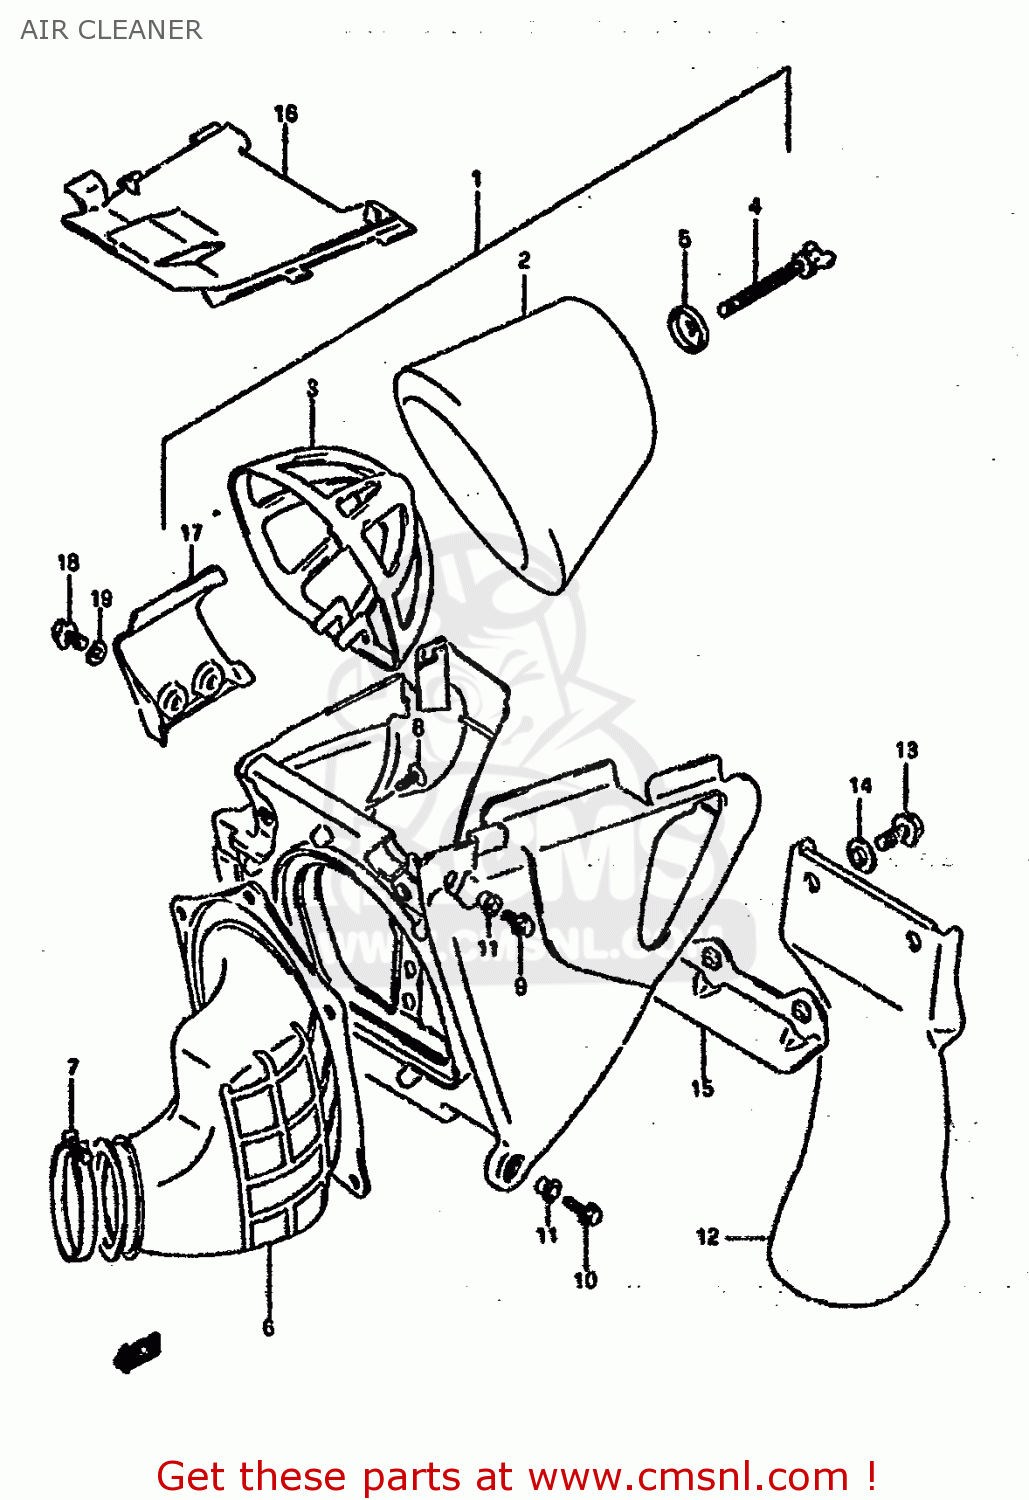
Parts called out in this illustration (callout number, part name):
1	CLEANER ASSEMBLY
2	FILTER ASSY
3	HOLDER,FILTER
4	BOLT,WING
5	WASHER,AIR CLEANER
6	TUBE,OUTLET
7	CLAMP
8	SCREW
9	BOLT
10	SCREW
11	WASHER
12	GUARD,MUD
13	BOLT
14	WASHER
15	PLATE,MUDGUARD
16	CAP,AIR CLEANER
17	COVER,AIR CLEANER,R NO.2
18	BOLT
19	WASHER
